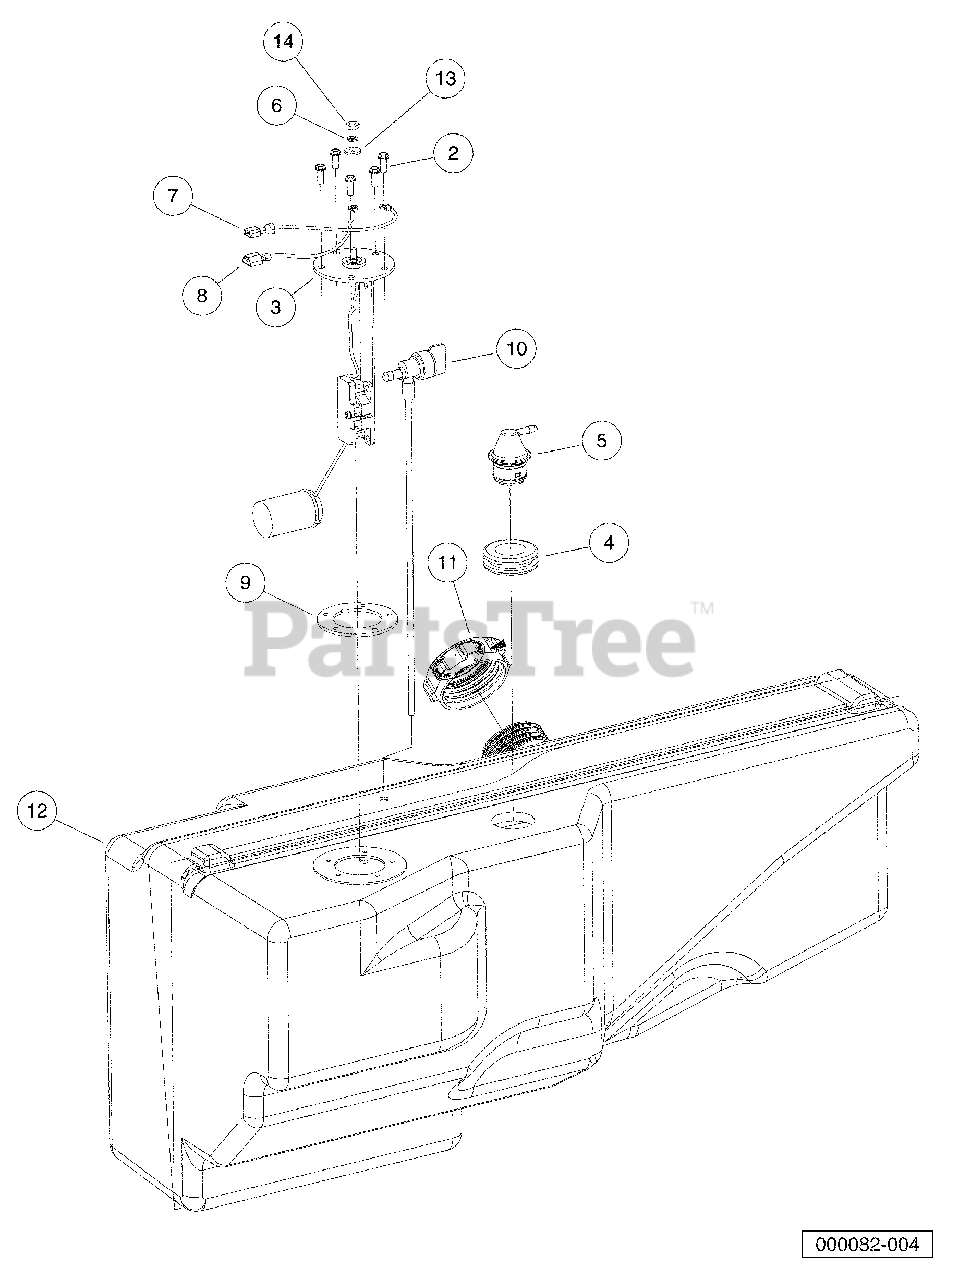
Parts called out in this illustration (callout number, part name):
1	Asm, Tank, Fuel, Gas, 4x4
2	Screw, #10-16 Hex-Head Hi-Lo
3	Sending Unit, Fuel Level *.
4	Insulation Grommet
5	Vent, Fuel Tank
6	Washer, #10 Split Lock
9	Gasket, Rubber
10	Valve, Pickup Tube, Fuel
11	Cap, Fuel Tank, Gasoline
13	Washer, #10 Type A Flat
14	Nut, #10-32 Brass Hex.
